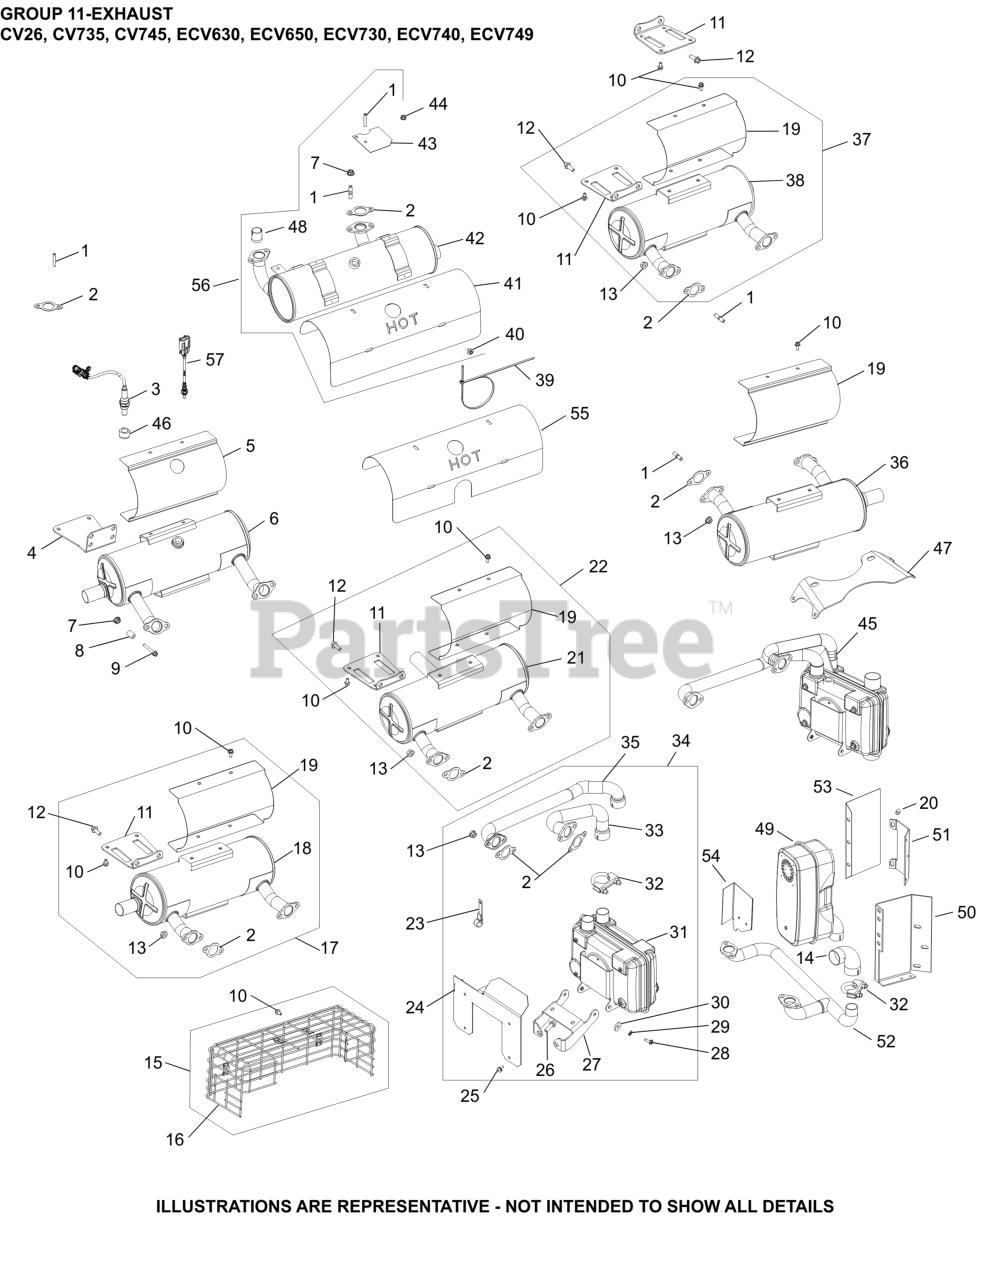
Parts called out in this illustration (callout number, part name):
1	STUD, METRIC EXHAUST
3	SENSOR, OXYGEN (M18 x 1.5 THREADS)
7	NUT, HEX FLANGE LOCK (M8)
9	SCREW, FLG M6X1.0X40
48	LINER, EXHAUST PORT
NI	GASKET, EXHAUST MANIFOLD
